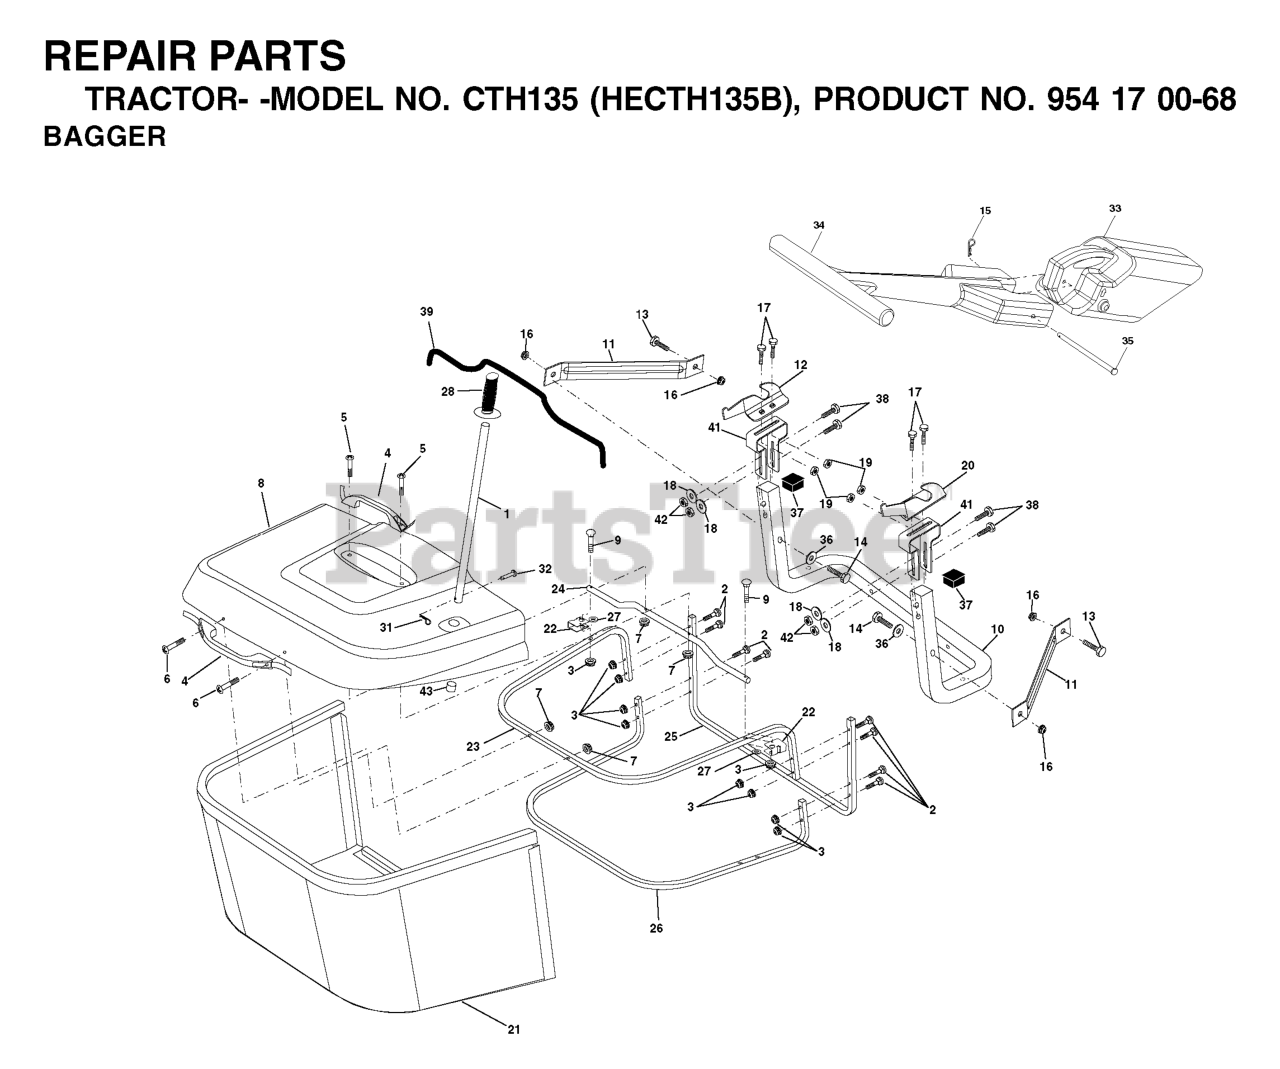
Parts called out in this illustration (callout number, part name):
1	TUBE HANDLE BAGGER
2	Bolt Carriage 1/4-20 x 2.0 Gr.5
3	NUT T
4	HANDLE.BAGGER.W/LVRS.BLK.CRD
5	SCREW.PAN.HEAD
6	REPL BY 532 75 00-29
8	COVER
9	Bolt Carriage 1/4-20 x 2.25d x Gr.5
10	TUBE
11	BRACKET.SUPPORT.UPPER.BAG.CRD
15	RETAINER-SPRNG RB
16	NUT LOCK FLG 3/8-16 UNC
17	RP BOLT 5/16-18 X3/4 ZN/YEL GR
18	WASHER M
19	NUT LOCK HEX FLANGE 5/16-18
20	BRACKET
21	BAG
22	BRKT.SIDE.BAG.CRD
23	TUBE.UPPER.BAG.CRD
24	TUBE.PIVOT.BAG.CRD.BLACK
26	TUBE.LOWER.BAG.CRD
28	Grip Handle Black
31	RETAINER M
32	RIVET,DRILLED
33	PLUG.MULCHER.92 CRD
34	HANDLE.MULCHER.92.CRD (2 2)
36	WASHER
37	Plug Support Bagger CRD
38	BOLT.5/16-18X2.5
39	TRIM
40	TRIM
41	BRKT.VERT.ADJ.BAGGER.CRD
42	NUT.71038.31-18.HEX.NYLOCK
